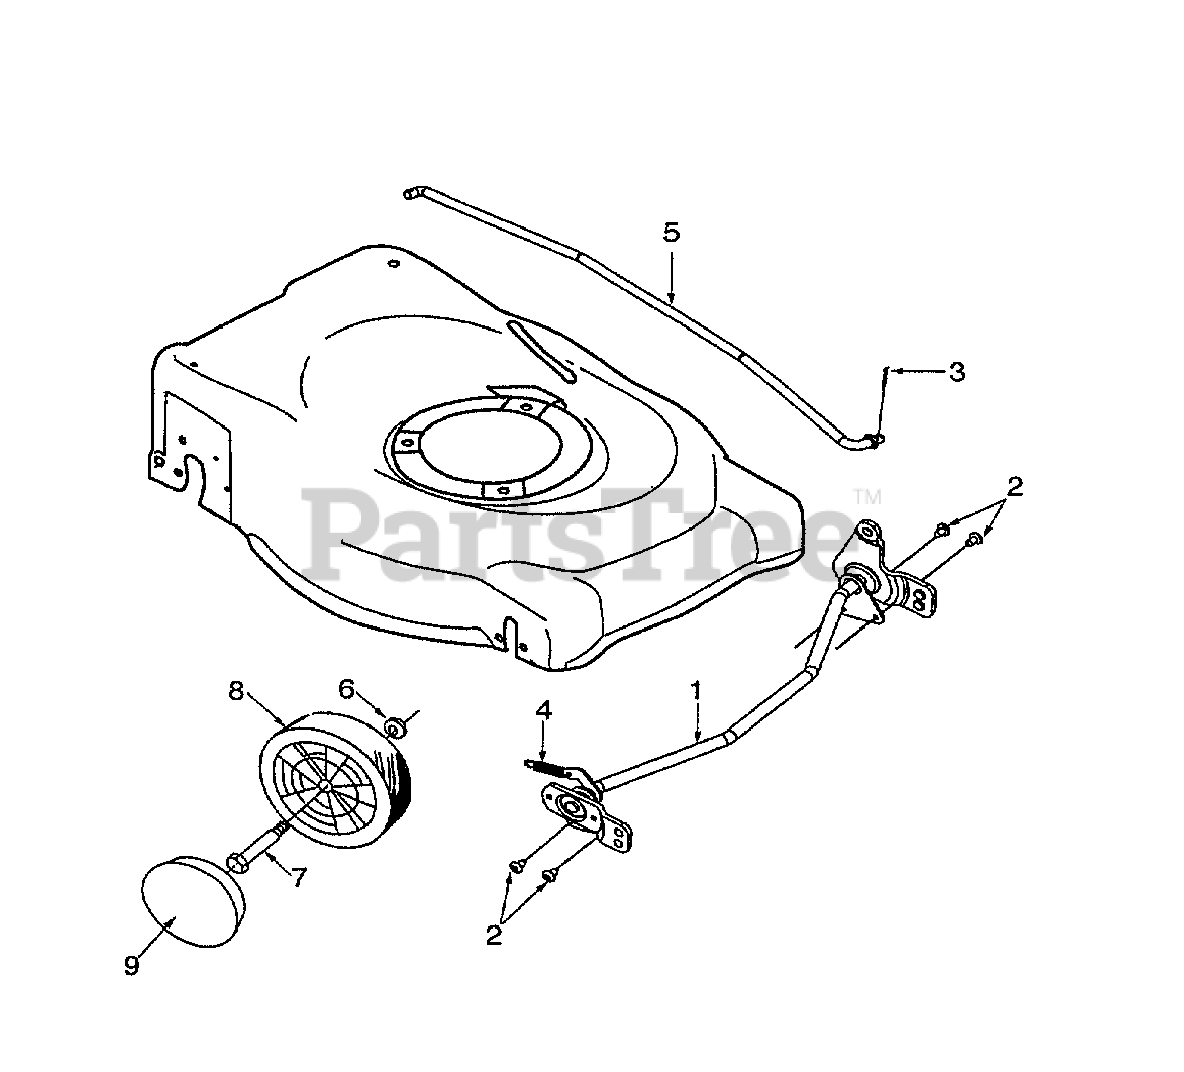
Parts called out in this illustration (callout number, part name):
2	AB Pan Scr. 1/4-14 x .50 Lg.
3	Cotter Pin .072 x 1.12 Lg.
4	Ext. Spring
5	Adj. Rod
6	Spr. Washer
7	Shl. Bolt .498 x 1.445 3/8-16
8	Wheel Ass'y - Complete
9	Hub Cap
